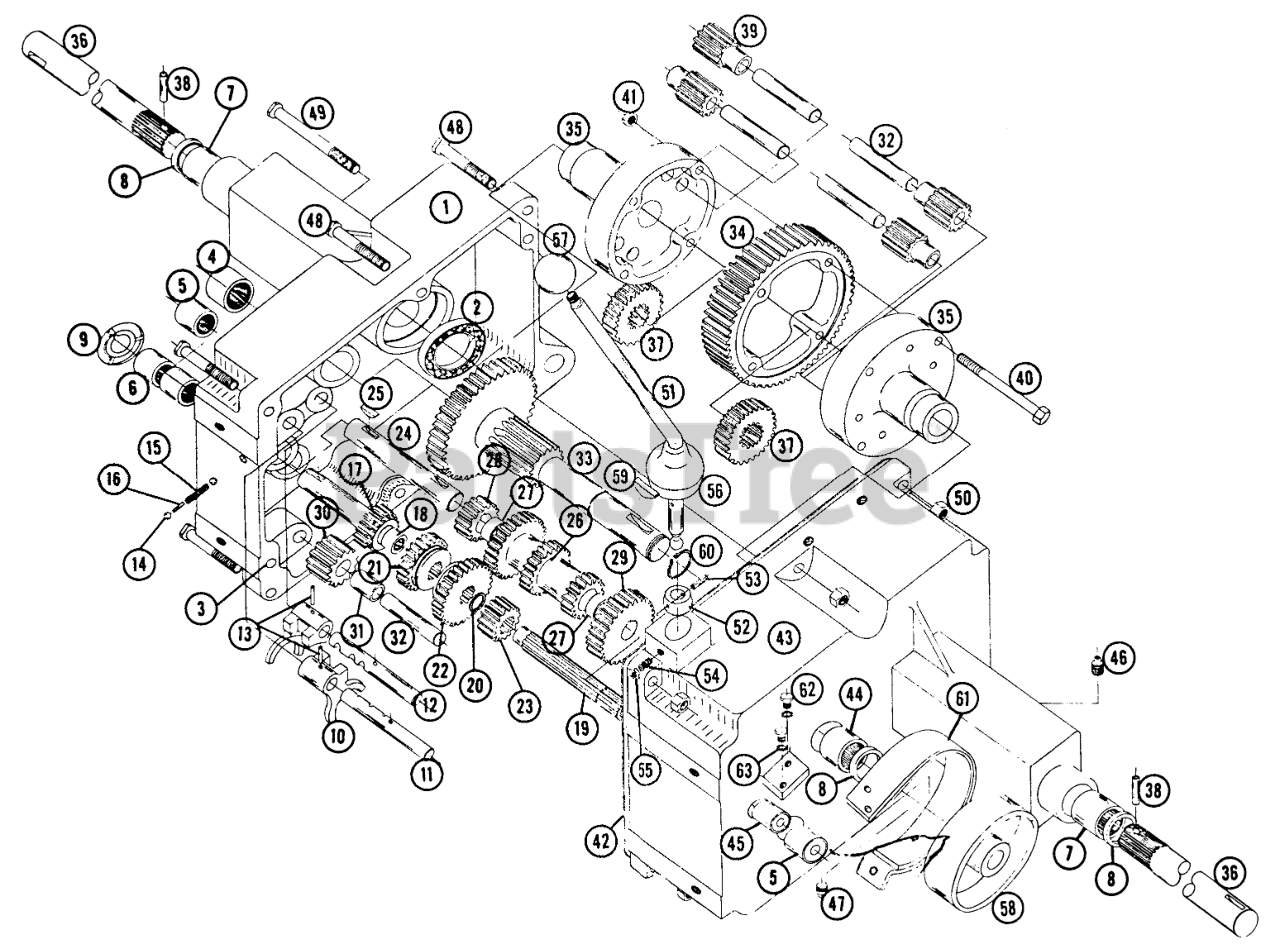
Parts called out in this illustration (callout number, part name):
3	PIN-DOWEL
4	BEARING-NEEDLE
5	BEARING-NEEDLE
7	BEARING-NEEDLE
10	FORK-SHIFT
13	PIN-ROLL
14	BALL-DETENT
18	BEARING-NEEDLE
20	Snap Ring 3/4 I.D.
23	GEAR
25	Key
27	BUSHING-BRONZE
29	GEAR-CLUSTER SHAFT
30	GEAR/BUSHING ASM-REVERSE IDLER
31	BUSHING
32	PIN-DIFFERENTIAL
34	SVC BULLT 394
35	DIFFERENTIAL CASE
37	AXLE GEAR
42	GASKET-TRANSMISSION
46	Plug 1/4 Pipe
47	Plug 3/8 Pipe
48	Bolt, 3/8 16 x 2
49	Bolt Hex 3/8-16 x 1
53	Roll Pin
54	Screw Soc. Hd.-Set 1/4-20 x 3/4
55	Nut 1/4-20
56	COVER-DUST
59	KEY-WOODRUFF
60	Snap Ring 1" Shaft
62	Bolt-1/4-20 x 5/8
63	Lockwasher
